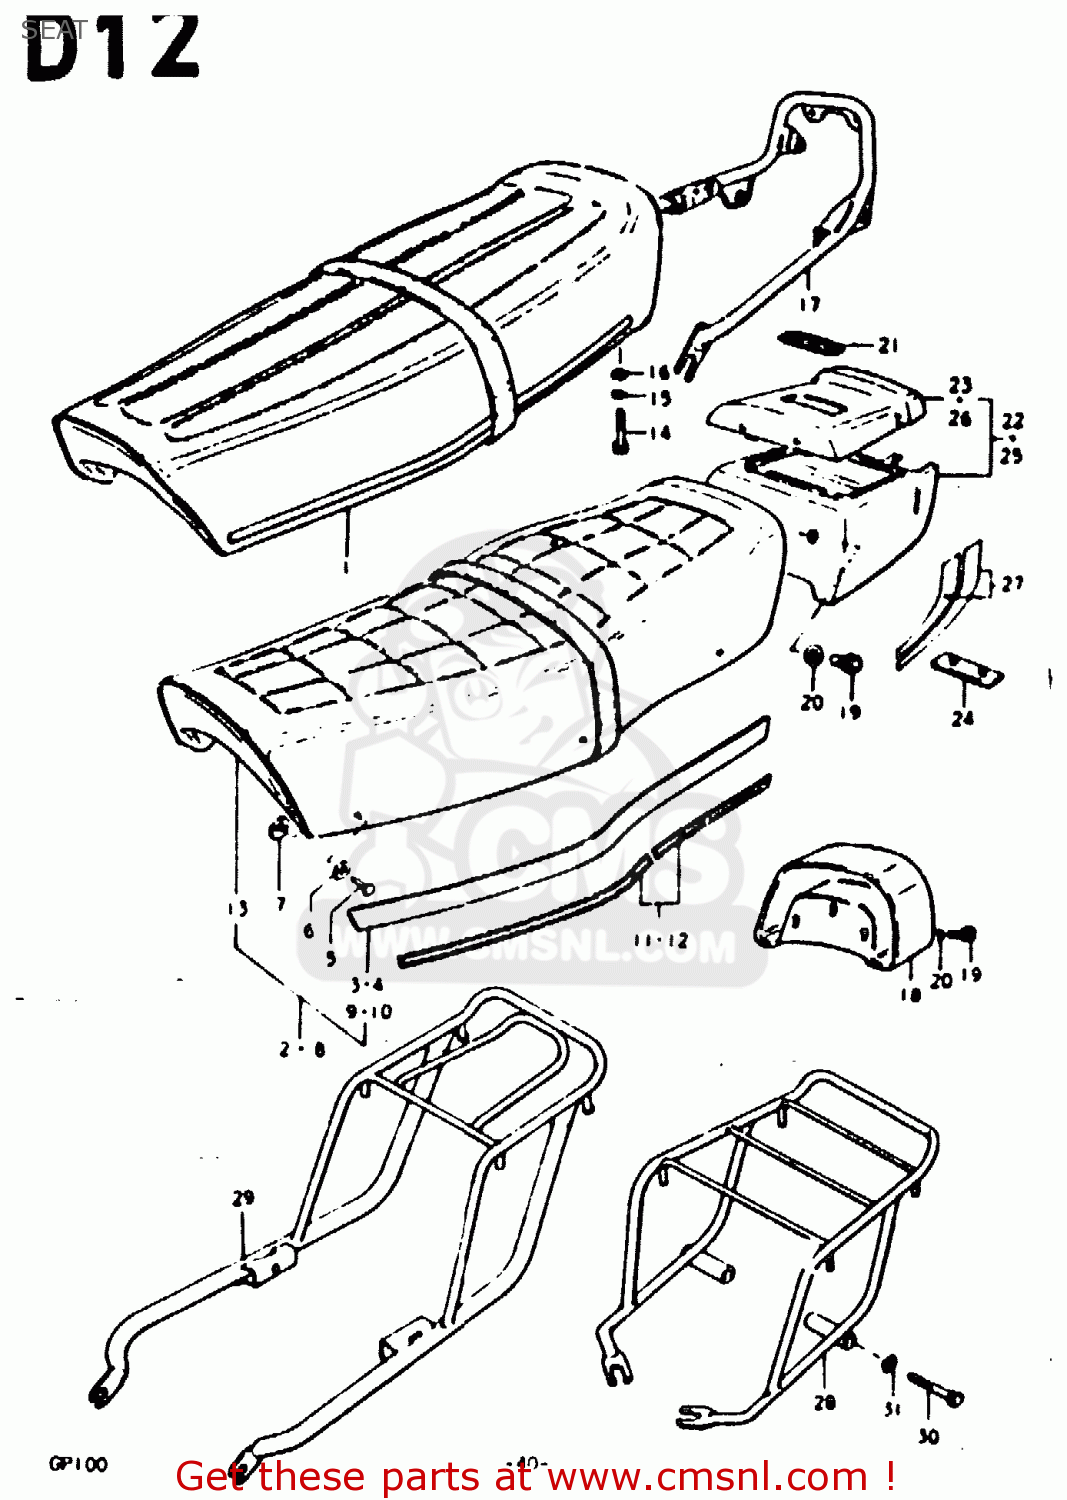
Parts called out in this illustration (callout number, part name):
1	SEAT ASSY (TYPE:NON MOLD)
14	BOLT 8X40
15	LOCK WASHER
16	WASHER
17	BAR, REAR COMBINATION LAMP
28	CARRIER, SPORTS
30	BOLT
31	LOCK WASHER
